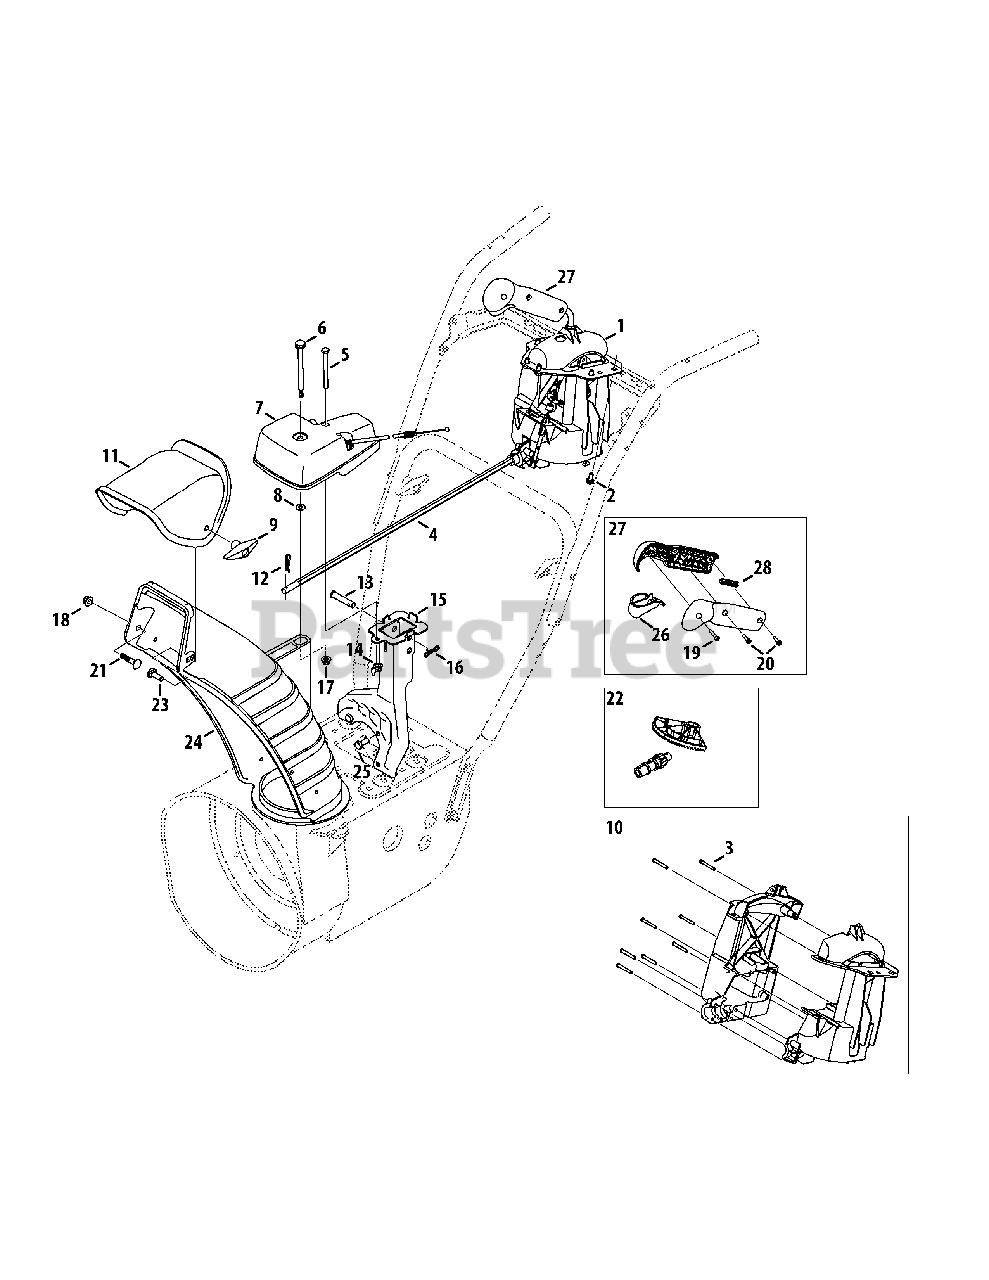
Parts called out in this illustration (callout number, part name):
1	2-Way Chute Control Assembly
2	Hi-Lo Screw, 1/4-15 x 0.5
3	Screw, #8-18 x 1.250
4	Chute Rod
5	Hex Screw, 1/4-20 x 3.00
6	Flange Shoulder Screw
7	Gearbox Assembly
7	Screw-Hl #12-16 .7
7	Shaft-Worm Drv Hex
7	Nut-Hex Ins-L
7	Gear-14T Helical
7	Gear-Worm
7	Cover-Chute Grbx
7	Spring-Torsion
7	Washer-Fl
7	Bolt-Shoulder
7	Flange Bearing
7	Cable-Chute Lock
7	Bracket-Rotate Grb
7	Pawl-Chute Lock
7	Brg-Hex Flange
8	Flat Washer, .25 x .630 x .0515
9	Wing Knob
10	Handle Housing Assembly
11	Upper Chute
12	Cotter Pin
13	Clevis Pin
14	Wing Nut, 1/4-20
15	Chute Support Bracket
16	Bow Tie Cotter Pin
17	Flange Lock Nut, 1/4-20
18	Flange Lock Nut, 5/16-18
19	Screw, #8 x 1.00
20	Screw, Mach., #8-32 x .750
21	Carriage Bolt, 5/16-18 x .75
22	Gear Set Assembly
23	Carriage Bolt, 5/16-18 x 1.0
24	Lower Chute
25	Hex Screw, 5/16-24 x .750
26	Handle Lever
27	Handle Assembly
28	Handle Plunger
